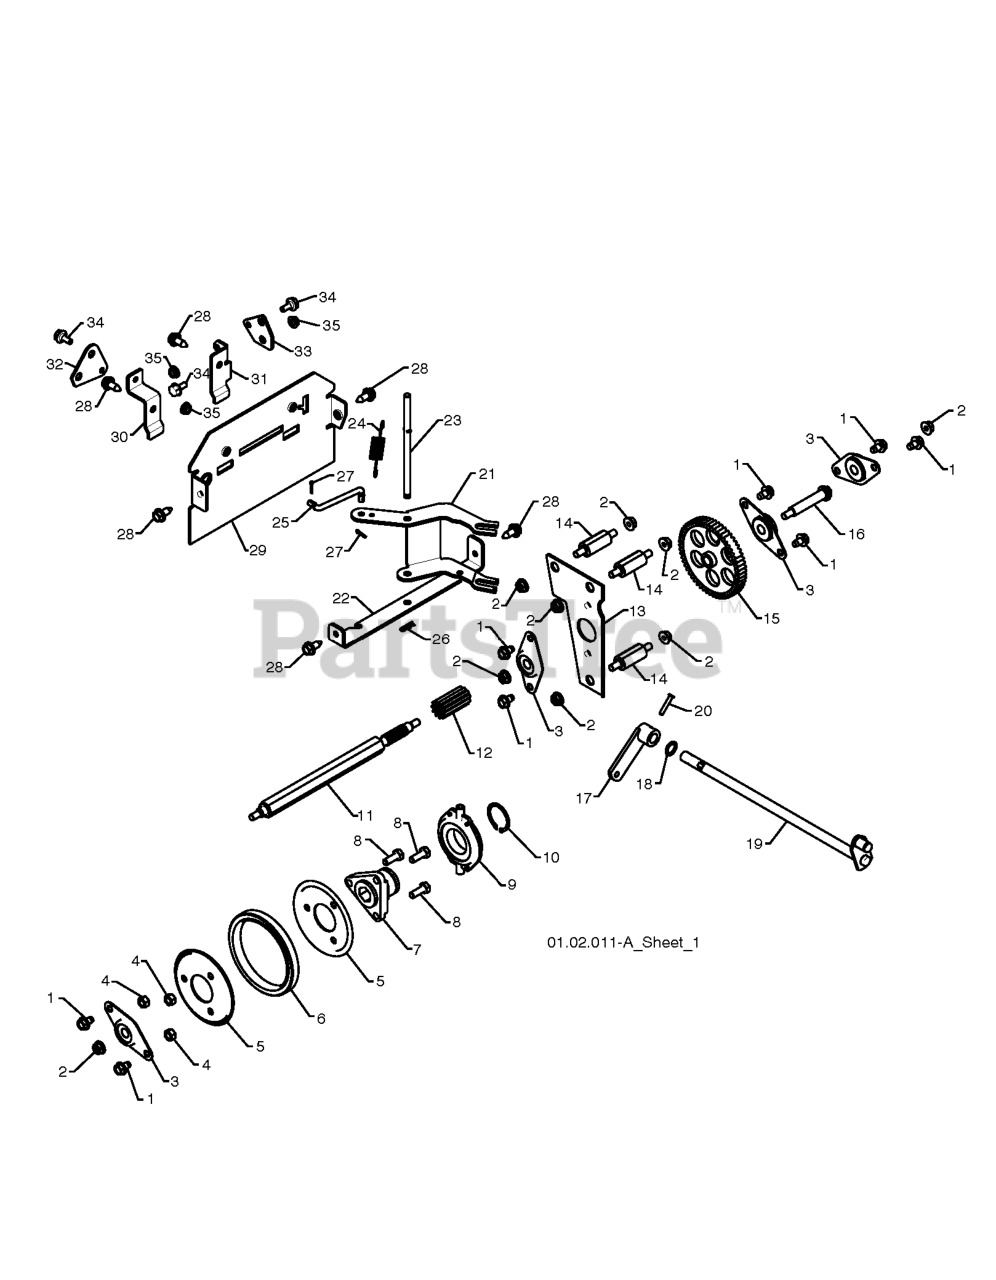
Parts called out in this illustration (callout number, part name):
1	Screw 5/16-18 x 1/2 Hex, Self Tapping 5/16-18 x 1/2
2	NUT.LOCK.5/16-18
3	BEARING, FLANGE
4	NUT.CENTERLOCK.5/16-
5	PLATE.RUBBER.WHEEL.BLACK
6	RING, RUBBER WHEEL
7	HUB, RUBBER WHEEL
8	BOLT
9	TRUNNION BEARING ASSY
10	RETAINING RING (2 2)(3 2)
11	SHAFT.HEX.LONG
12	GEAR, PINION
13	PLATE.AUXILIARY.
14	SPACER, PLATE
15	GEAR, INTERMEDIATE
16	SHAFT, AUXILIARY
17	ARM, AUGER CONTROL
18	THRUST WASHER
19	CONTROL.SHAFT.ASM
20	CLEVIS PIN
21	RP SHIFTER LEVER
22	BRACKET.SHIFT.PIVOT.BLACK
23	PIN, PIVOT
24	SPRING, BIAS
25	LINK, SPEED CONTROL
26	RETAINER CLIP PM
27	RETAINER CLIP
28	BOLT.HEX.HD.WASHER.5/16-18X.75
29	PLATE.REAR.SNOW.PNT.ORANGE
30	RP BRACKET.SHIFTER.PLATE
31	BRACKET.CLUTCH.PLATE
32	PLATE.SHIFTER.YZ
33	PLATE.CLUTCH.
34	BOLT.SHOULDER.3/X.25
35	NUT.HEX.FLANGE.1/4
